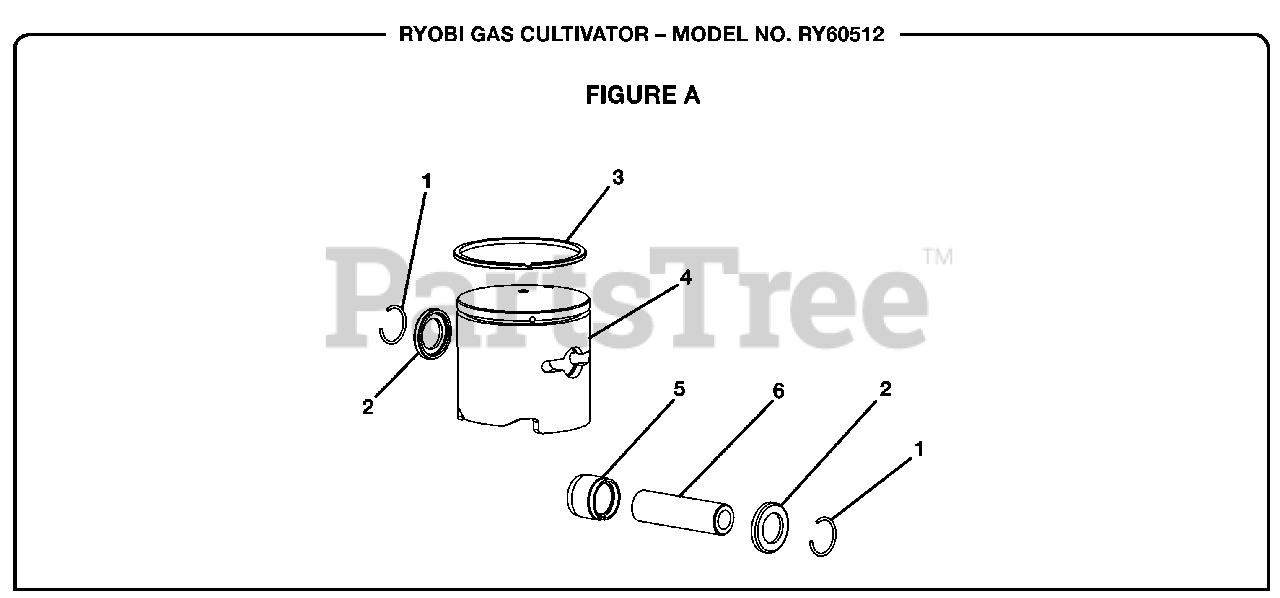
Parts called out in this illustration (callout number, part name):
1	Wrist Pin Clip Ring
2	Washer
3	Piston Ring
5	Needle Bearing (Id 8 x 8.8)
6	Wrist Pin
